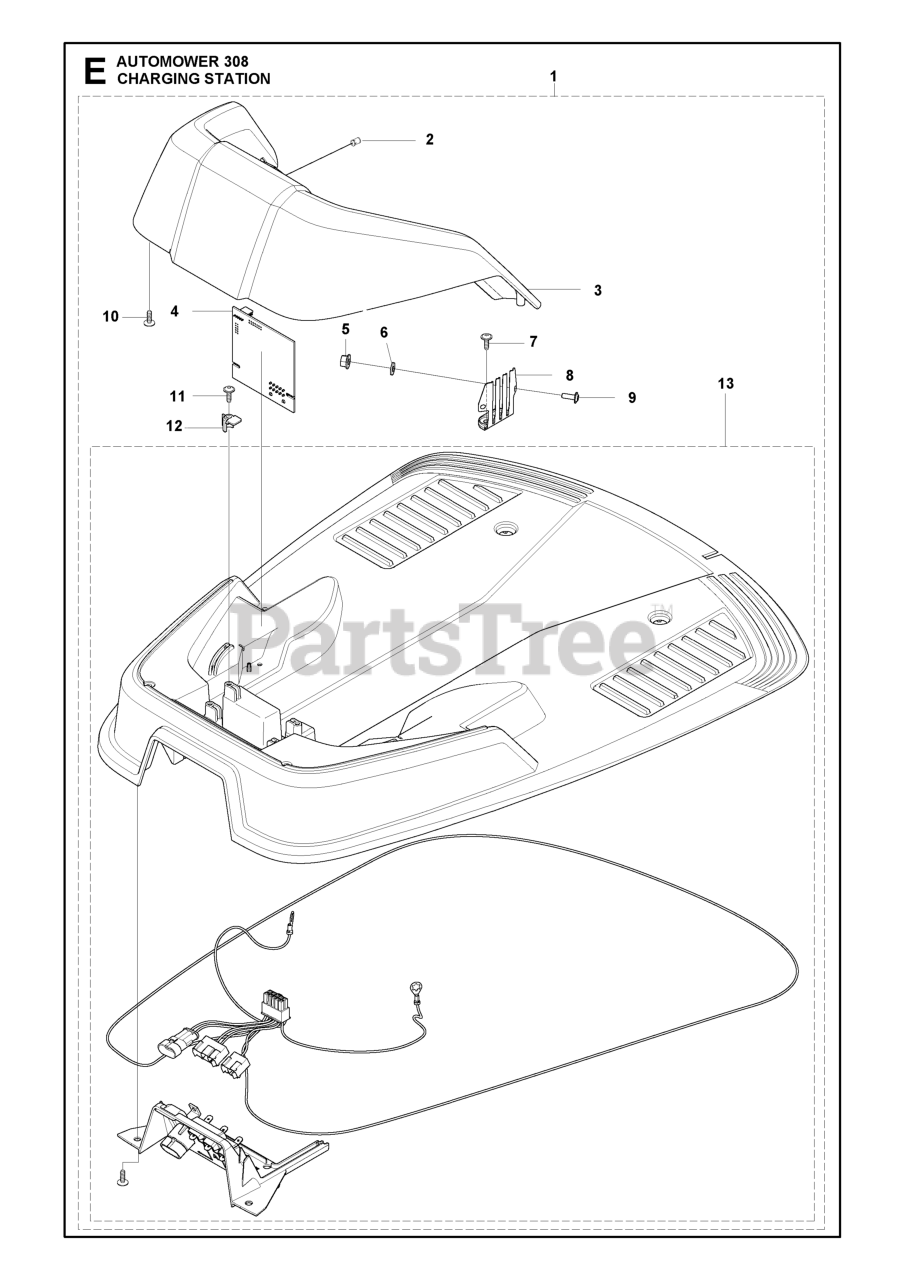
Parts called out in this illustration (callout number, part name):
2	LENS
6	SCREW 14MM
7	CONTACT CHARGER STATION CONTAC
8	SCREW 14MM
11	SCREW 14MM
13	SCREW 14MM
15	SCREW 14MM
